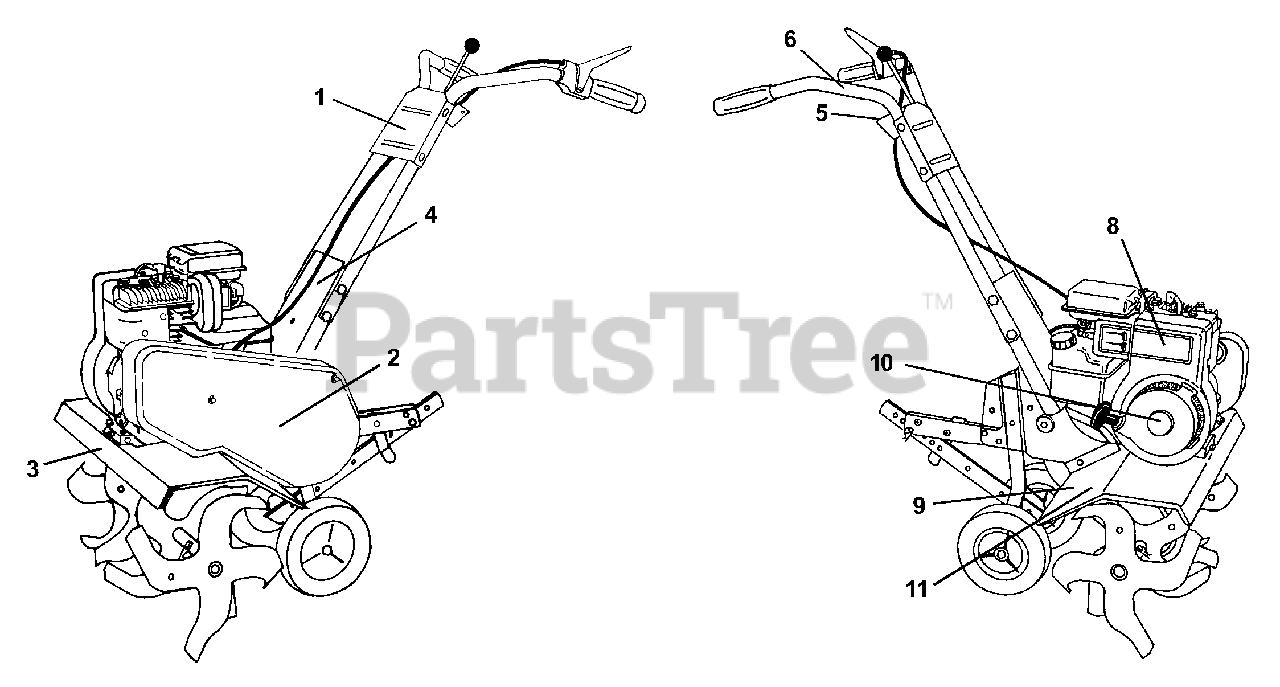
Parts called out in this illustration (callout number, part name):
1	Decal, Logo
2	Decal, Logo
3	Decal, Description
4	Decal, Forward Reverse
5	Decal, Reverse, Tine Control
6	Decal, Hand Placement
8	Decal, 5 HP
9	Decal, Warning, Rotating Tines
10	Decal, Briggs & Stratton
11	Decal, Warning, Tilling
